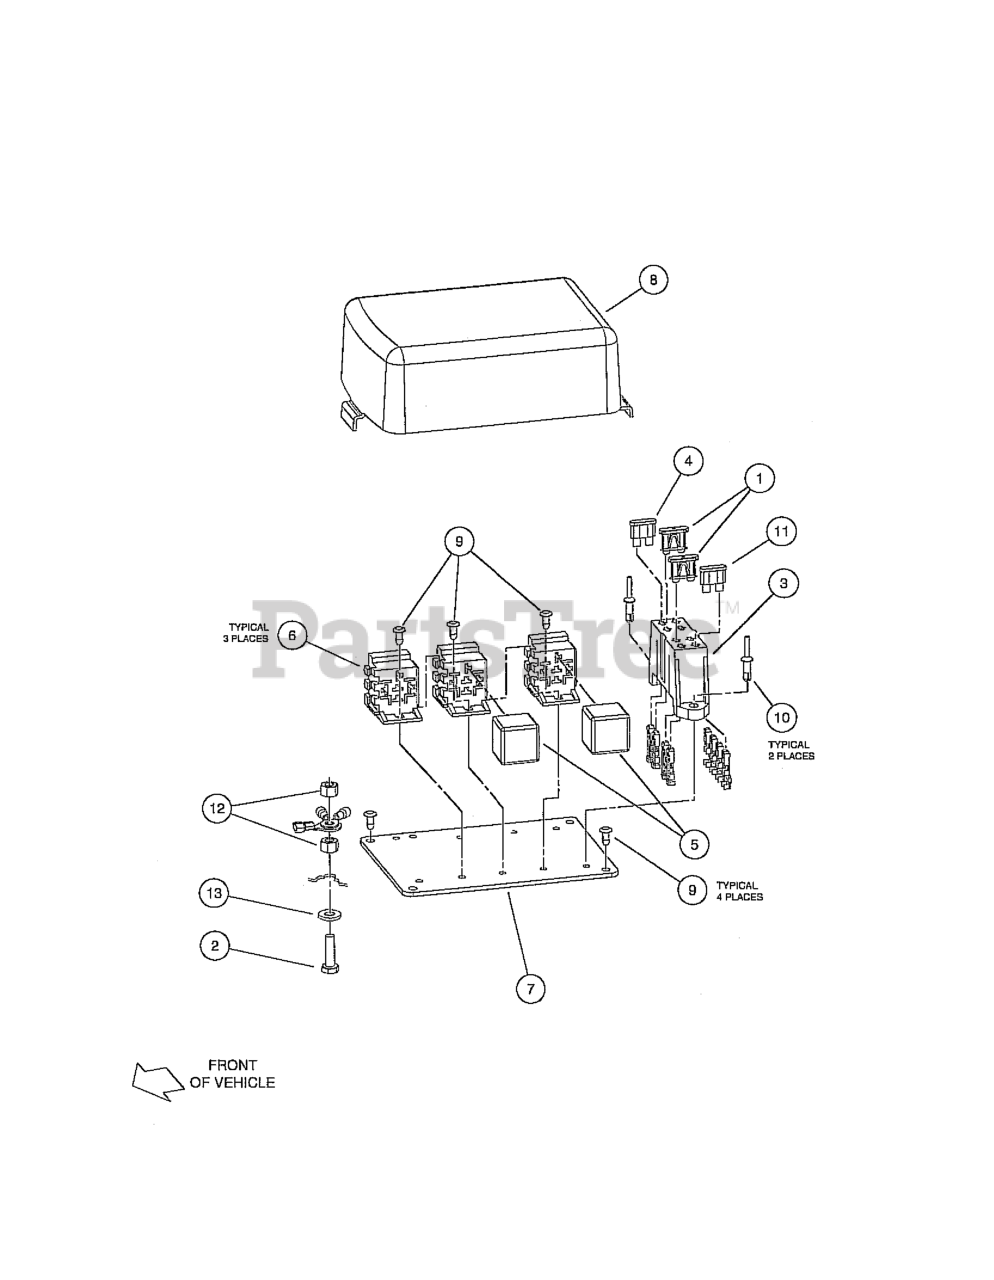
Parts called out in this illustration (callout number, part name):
1	10 AMP FUSE
3	FUSE BLOCK
4	FUSE - 20 AMP
5	RELAY, MINI ISO, SPDT
7	PLATE, ELECTRICAL
8	COVER, ELECTRICAL
9	FASTENER, PUSH-IN
10	RIVET, DRIVE
11	FUSE, ATC/ATO, 25A
12	LOCKNUT, 1/4-20 DIMPLED
13	WASHER 1/4 FLAT
